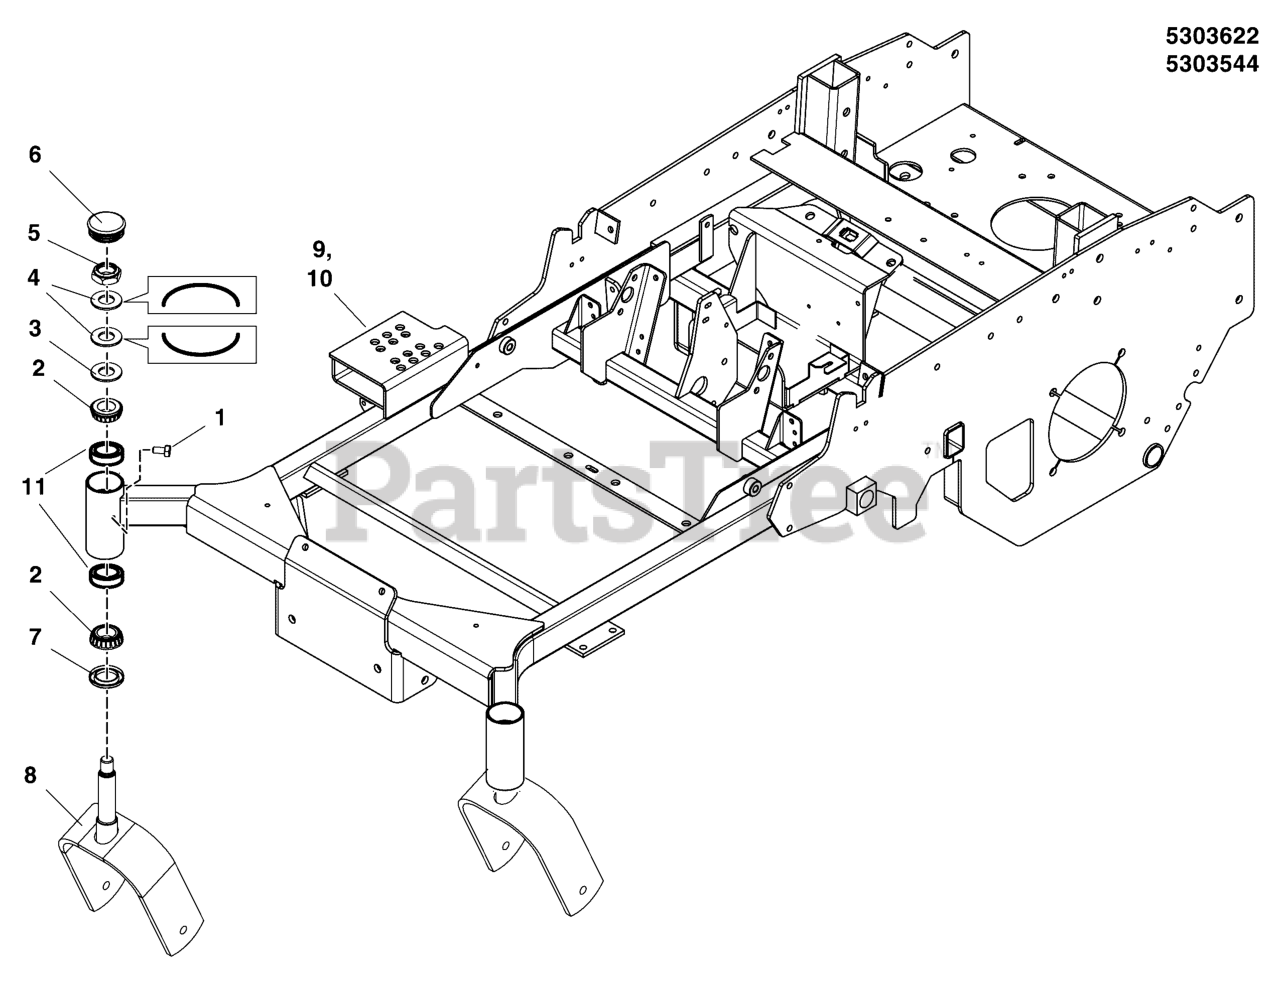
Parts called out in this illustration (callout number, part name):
1	BOLT, 1/4-28 X 1/2, GD5 YZ
2	BEARING, TAPERED ROLLER, 1
3	WASHER, 3/4 SAE
4	WASHER, BELLEVILLE - 1.500 X .755
5	NUT, 3/4-16, HEX JAM NYLON LOCK
6	CAP, GREASE, LOW PROFILE
7	SEAL, GREASE
8	WELD, CAST YOKE - RED
9	WELD, MAIN FRAME, S150XT - RED
10	WELD, MAIN FRAME, S150XT, 48 - RED
11	CUP, BEARING (SV)
